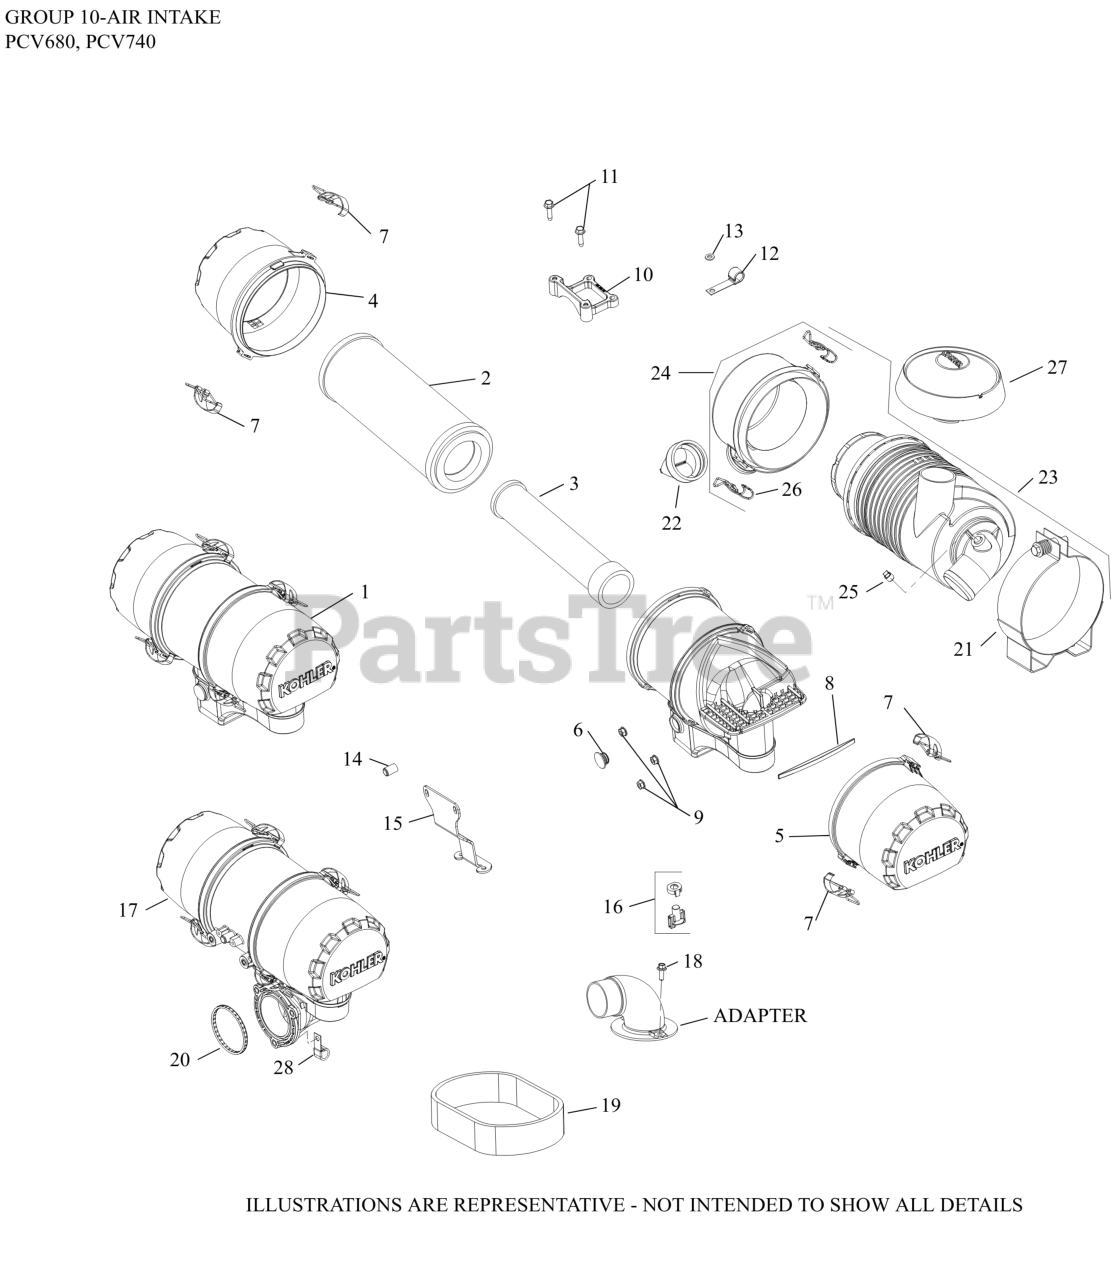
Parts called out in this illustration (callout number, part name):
2	ELEMENT, AIR FILTER - PRIMARY
3	ELEMENT, AIR FILTER - SAFETY
4	COVER, AIR FILTER
5	COVER, RAIN CAP
6	PLUG, HOLE
7	CLIP ASSEMBLY
8	DAMPER, FOAM INSERT
9	NUT, FLG M6X1.0
12	CLIP, CABLE
13	WASHER, FLAT 1/4" (O.D. 1/2")
14	CAP, MASKING
15	BRACKET, SUPPORT
17	FILTER ASSEMBLY, AIR - OIL FILTER SIDE
18	SCREW, FLG M6X1.0X16
20	O-RING (HDAC SEAL-EFI)
